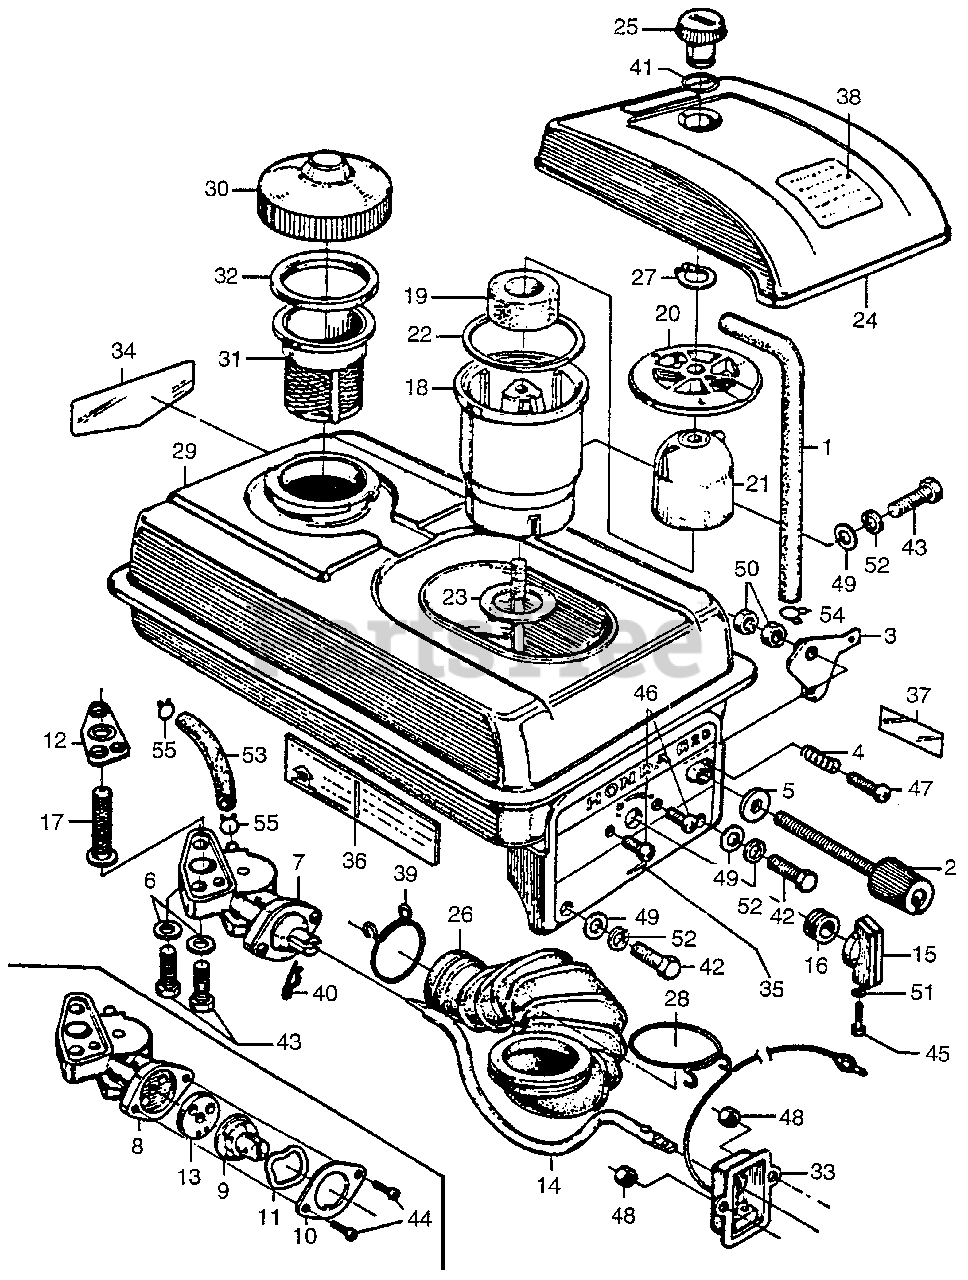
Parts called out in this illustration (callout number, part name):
1	PIPE, BREATHER (NOT AVAILABLE)
2	SHAFT, CONTROL (NOT AVAILABLE)
3	GUIDE, CONTROL (NOT AVAILABLE)
4	SPRING, STOPPER (NOT AVAILABLE)
5	RUBBER, FRICTION
6	GASKET, STRAINER SETTING (NOT AVAILABLE)
7	PETCOCK ASSY. (NOT AVAILABLE)
8	BODY, PETCOCK (NOT AVAILABLE)
9	LEVER, VALVE (NOT AVAILABLE)
10	HOLDER, LEVER
11	SPRING, PETCOCK LEVER
12	GASKET, FLANGE (NOT AVAILABLE)
13	GASKET, VALVE
14	SHAFT, PETCOCK
15	KNOB, PETCOCK (NOT AVAILABLE)
16	GROMMET, PETCOCK SHAFT
17	FILTER, CHECK (NOT AVAILABLE)
18	PAN, AIR CLEANER OIL
19	ELEMENT, AIR CLEANER
20	SEPARATOR A (NOT AVAILABLE)
21	SEPARATOR B
22	GASKET A, CLEANER (NOT AVAILABLE)
23	GASKET B, CLEANER (NOT AVAILABLE)
24	COVER, AIR CLEANER *NH31* (MCKINLEY WHITE) (NOT AVAILABLE)
25	NUT, CLEANER CAP
25	NUT, CLEANER CAP (NOT AVAILABLE)
26	TUBE, CONNECTING (NOT AVAILABLE)
27	CLIP, CLEANER (NOT AVAILABLE)
28	CIRCLIP (42MM) (NOT AVAILABLE)
29	TANK, FUEL *NH31* (MCKINLEY WHITE) (NOT AVAILABLE)
30	CAP, FUEL TANK (NOT AVAILABLE)
31	FILTER, FUEL
32	GASKET, FUEL FILTER (NOT AVAILABLE)
33	SWITCH ASSY., ENGINE
33	SWITCH ASSY., ENGINE (NOT AVAILABLE)
35	PLATE, CAUTION
37	MARK, THROTTLE (NOT AVAILABLE)
38	PLATE, CAUTION (NOT AVAILABLE)
39	CIRCLIP (34MM)
40	PIN, LOCK (10MM)
41	O-RING (11.5X2)
42	BOLT, HEX. (6X16)
43	BOLT, HEX. (6X20)
44	SCREW, PAN (3X6)
45	SCREW, PAN (3X16) (NOT AVAILABLE)
46	SCREW, PAN (4X8)
47	SCREW, PAN (4X12)
48	NUT, HEX. (4MM)
49	WASHER, PLAIN (6MM)
50	NUT, HEX. (6MM)
51	WASHER, SPRING (3MM)
52	WASHER, SPRING (6MM)
53	TUBE (4.5X130)
53	BULK HOSE, FUEL (4.5X3000) (4.5)
53	TUBE (4.5X60)
53	TUBE (4.5X95)
53	TUBE (4.5X105)
53	TUBE (4.5X190)
53	TUBE (4.5X200)
53	TUBE (4.5MMX95)
53	BULK HOSE, FUEL (4.5X3000) (4.5X60)
54	CLIP, TUBE (B12)
55	CLIP, TUBE (4.5)
55	CLIP, TUBE (B8)
